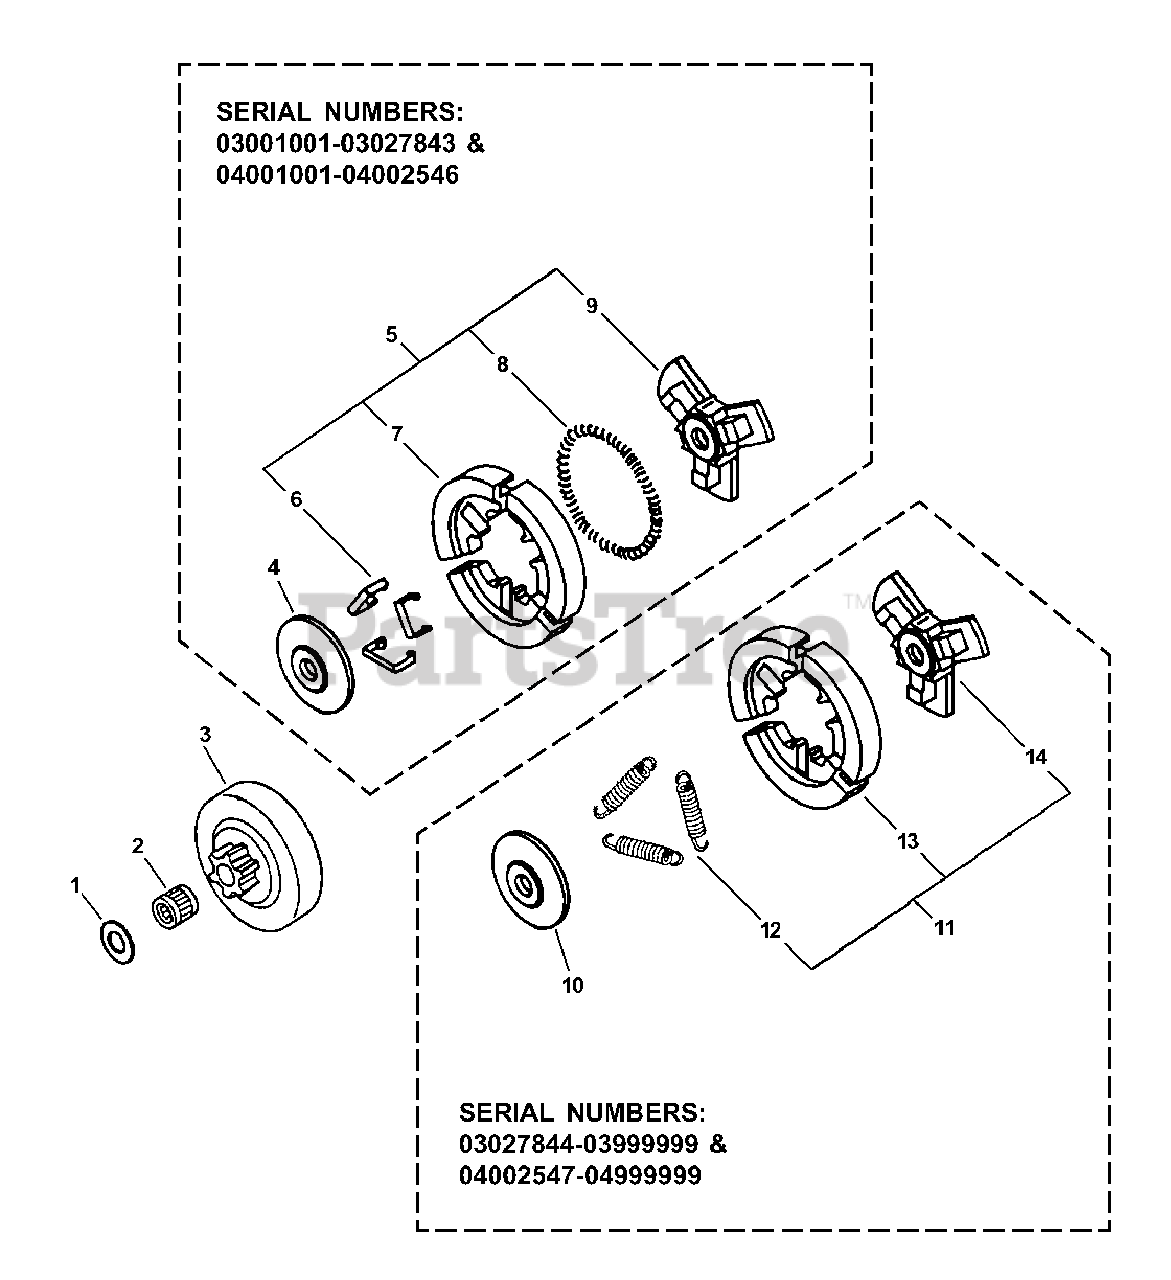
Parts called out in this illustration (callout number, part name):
1	WASHER 10.2×24.5×1.2
2	BEARING, NEEDLE 10×13×10
3	DRUM, CLUTCH 3/8"
4	PLATE, CLUTCH
5	CLUTCH ASSY
6	SPRING, FLAT
7	SHOE SET, CLUTCH (3PCS)
8	SPRING, TORSION
9	HUB, CLUTCH
10	PLATE, CLUTCH
11	CLUTCH ASSY
12	SPRING, CLUTCH
13	SHOE SET, CLUTCH (3PCS)
14	HUB, CLUTCH
